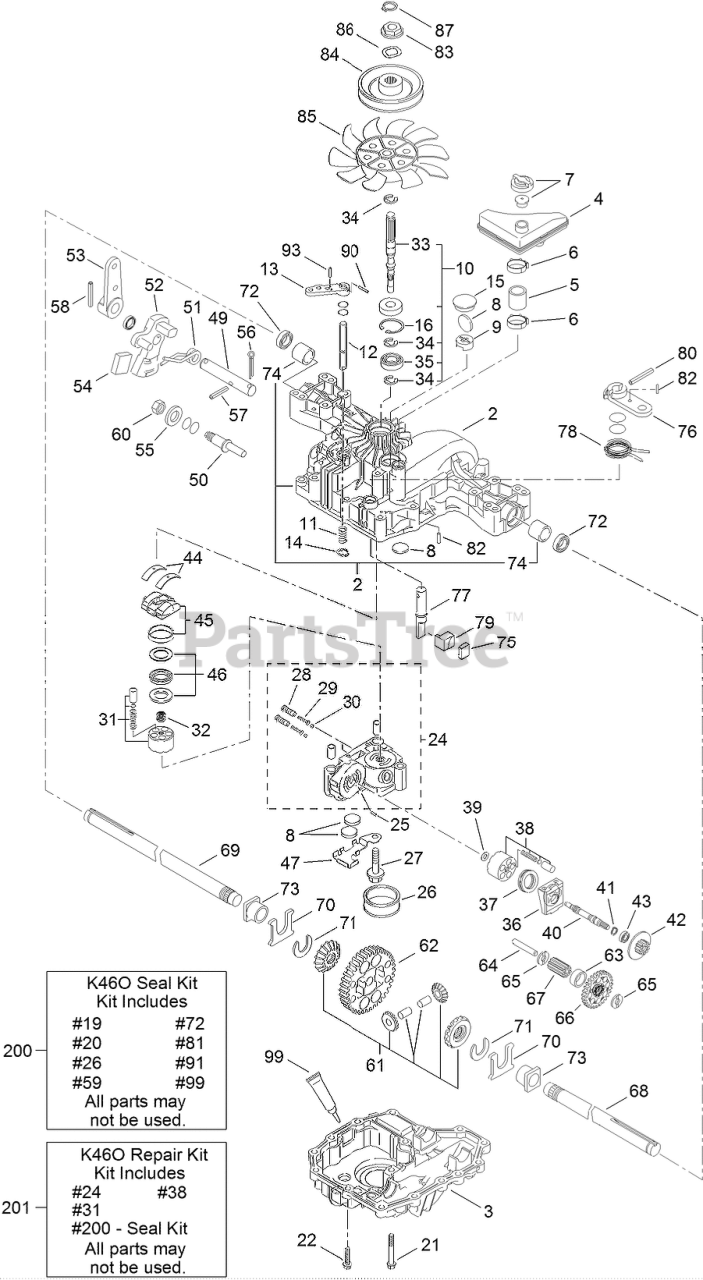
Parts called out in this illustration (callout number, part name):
2	UPPER CASE KIT
3	Housing-Lower
4	TANK-RESERVOIR
6	Clamp-Miniature
7	VALVE-VENT
8	Magnet
9	HOLDER-MAGNET
10	PUMP SHAFT/BEARING KIT
11	SPRING
12	Shaft-Bypass
13	Lever-Bypass
15	Plug-Bore
16	RING-SNAP
21	SCREW-TAPPING
22	SCREW-TAPPING
24	CENTER CASE W/BALL IDS KIT
26	FILTER
28	VALVE-IDS
29	SPRING-IDS
31	CYLINDER BLOCK (PUMP) KIT
32	Spring-Pump
33	Shaft-Pump
34	E-RING
35	BEARING
36	Housing
37	BEARING-THRUST
38	CYLINDER BLOCK KIT (MOTOR)
39	Washer
40	SHAFT-MOTOR
41	RING-SNAP
42	MOTOR-GEAR
43	BEARING
44	Metal-Thrust
45	Plate-Swash
46	THRUST BEARING (PUMP) KIT
47	HOLDER-MAGNET
49	SHAFT-CONTROL
50	FULCRUM
51	SPRING-TORSION
52	ARM-CONTROL
53	LEVER-CONTROL
54	PLATE-JERKY
55	WASHER
56	PIN-COTTER
57	SPRING PIN
58	PIN-ROLL
61	DIFFERENTIAL GEAR KIT
62	GEAR-FINAL
63	COLLAR-PINION, FINAL
64	SHAFT-REDUCTION
65	WASHER
66	GEAR-REDUCTION
67	GEAR-PINION, FINAL
68	SHAFT-AXLE, LEFT
69	SHAFT-AXLE, RIGHT
70	WASHER-THRUST
71	RING
72	SEAL
73	BUSHING
74	BUSHING
75	SHOE-BRAKE
76	LEVER-BRAKE
77	SHAFT-BRAKE
78	SPRING-RETURN, BRAKE
79	ACTUATOR-BRAKE
82	PIN-SPRING
83	COLLAR-SPLINE
84	PULLEY
85	FAN-WHITE
86	WASHER-WAVE
87	RING-SNAP
90	PIN-SPRING
99	SEALANT
200	SEAL KIT
201	REPAIR KIT
